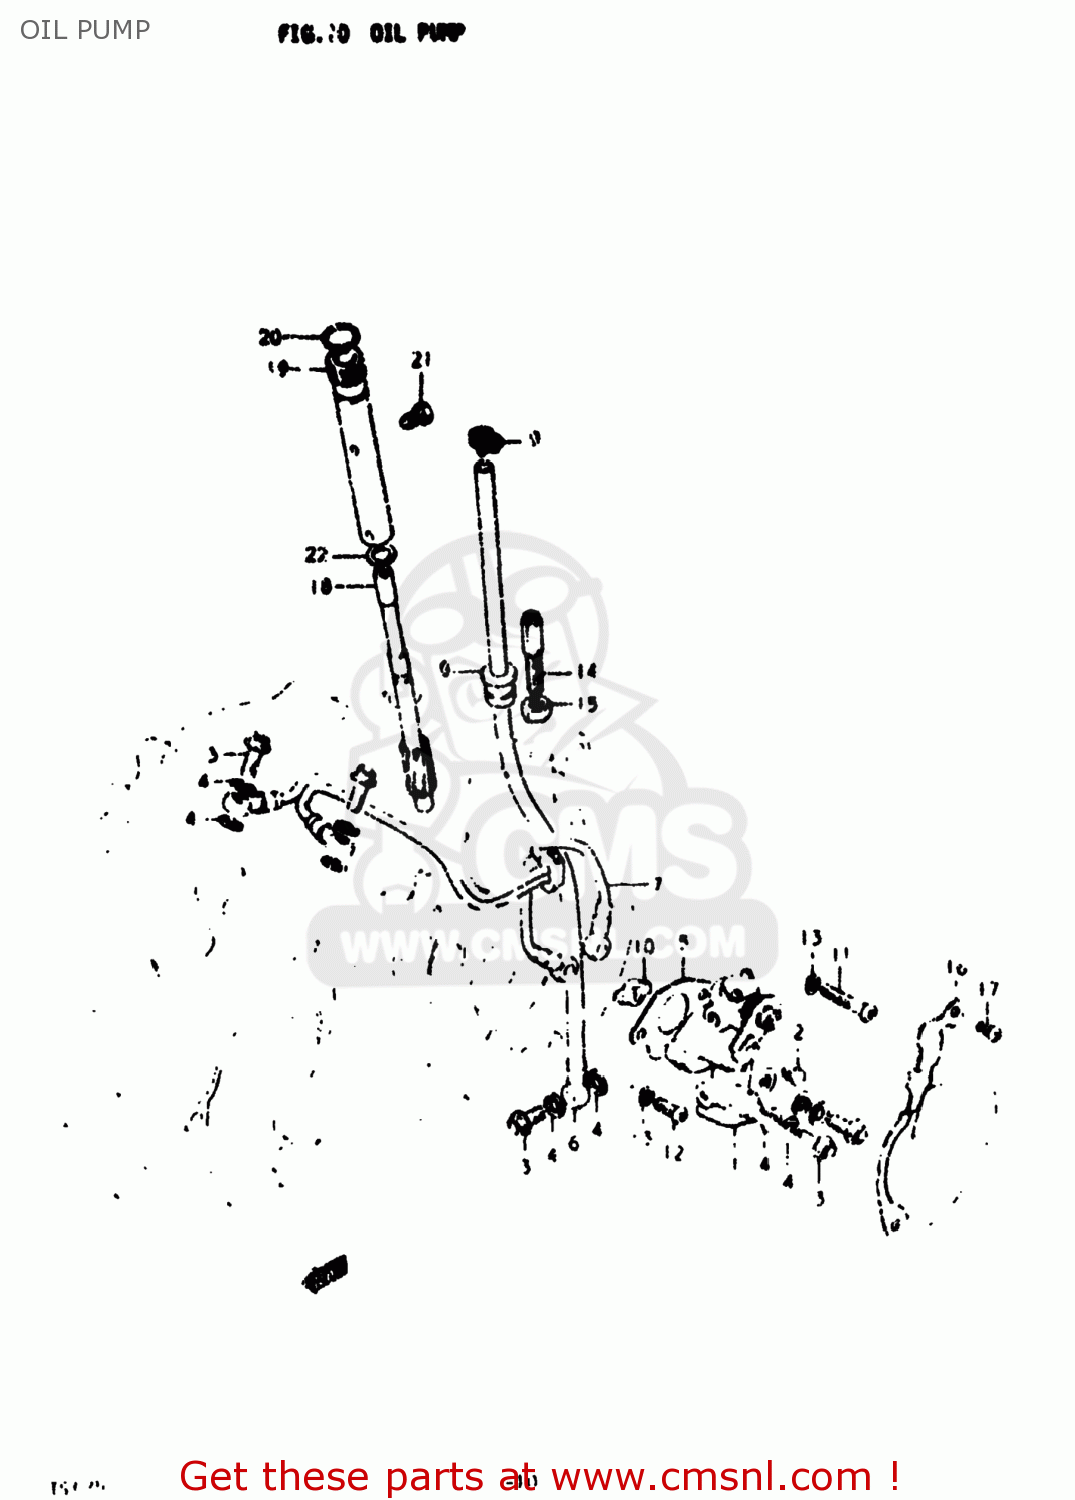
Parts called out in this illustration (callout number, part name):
1	PUMP ASSEMBLY,OIL
2	TERMINAL,CABLE
3	UNION BOLT
4	GASKET (NAS)
5	GASKET,OIL PUMP (MCA)
6	HOSE,OIL NO.1
7	HOSE,OIL NO.2
8	BUSHING
9	CLAMP
10	PIECE,OIL PUMP DRIVE
11	SCREW
12	SCREW
13	LOCK WASHER
14	BOLT
15	NUT
16	CAP,OIL PUMP INSPECTION
17	SCREW
18	GEAR,TACHOMETER DRIVEN
19	SLEEVE,TACHOMETER DRIVE
20	O RING(D:1.3,ID:9.6)
21	BOLT(6X12)
22	WASHER(8X13.7X1)
